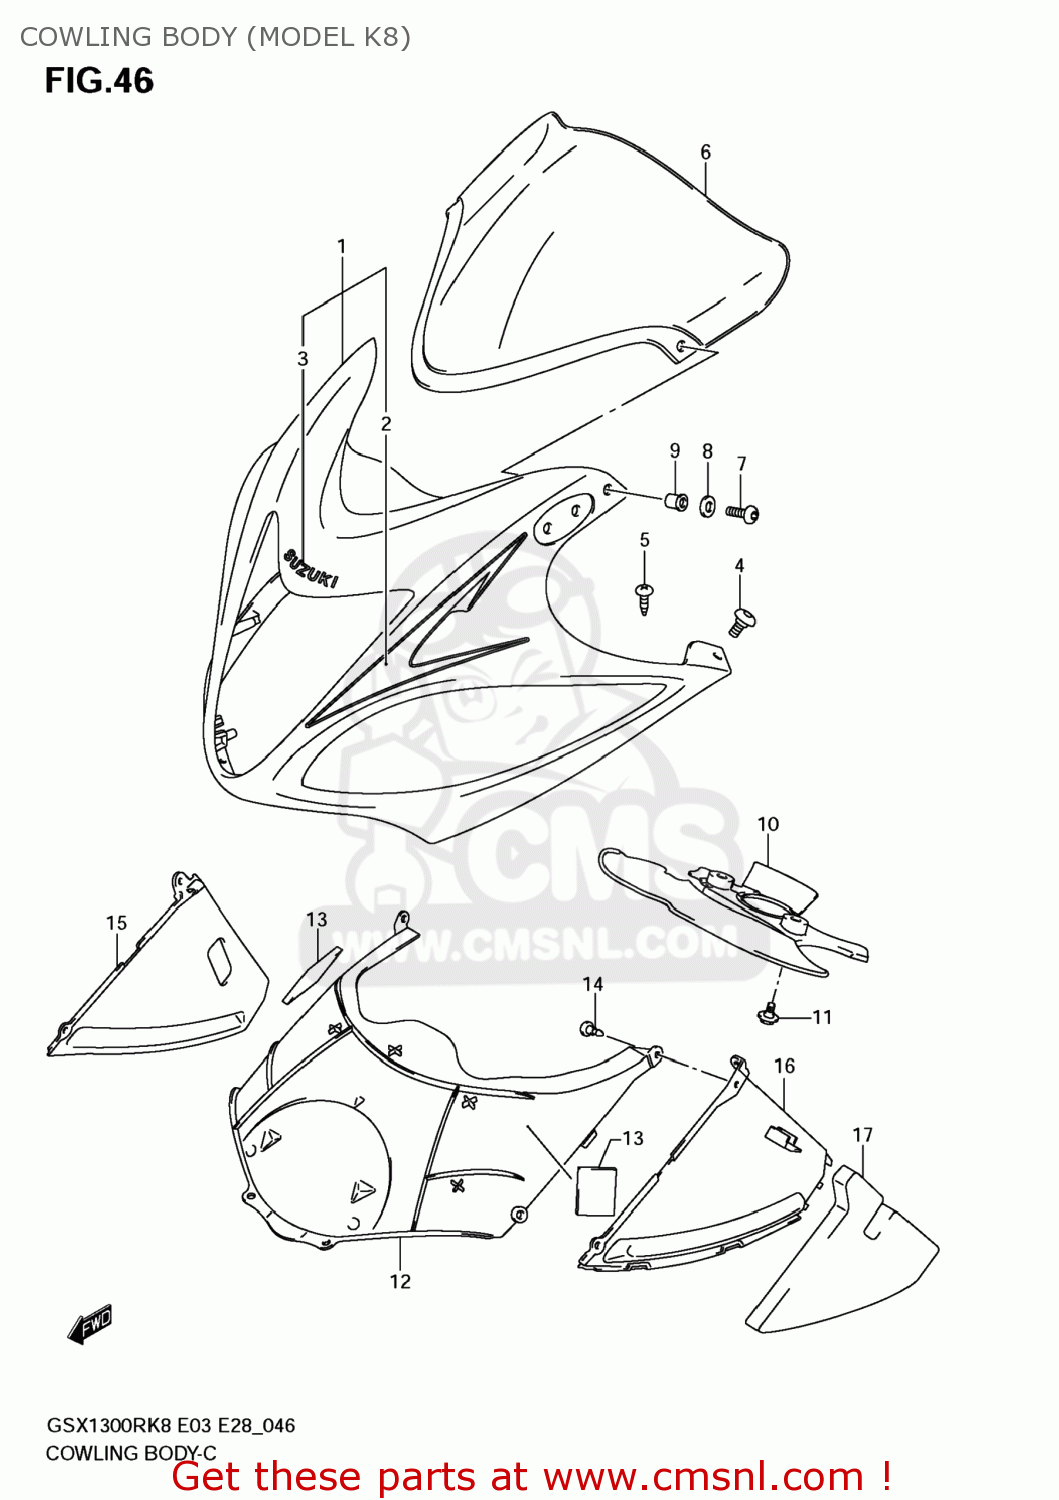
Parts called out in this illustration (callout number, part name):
1	COWLING ASSY,BODY
2	TAPE SET,BODY COWL
3	EMBLEM
4	SCREW(5X16)
5	SCREW
6	WINDSCREEN
7	SCREW(5X14)
8	WASHER
9	NUT
10	COVER,LWR BRACKET
11	BOLT
12	COVER,BODY COW
13	COVER,HARNESS
14	CLIP(BLACK)
15	COWLING,UNDER INNER,R
16	COWLING,UNDER INNER,L
17	CUSHION,INNER COWL,L
